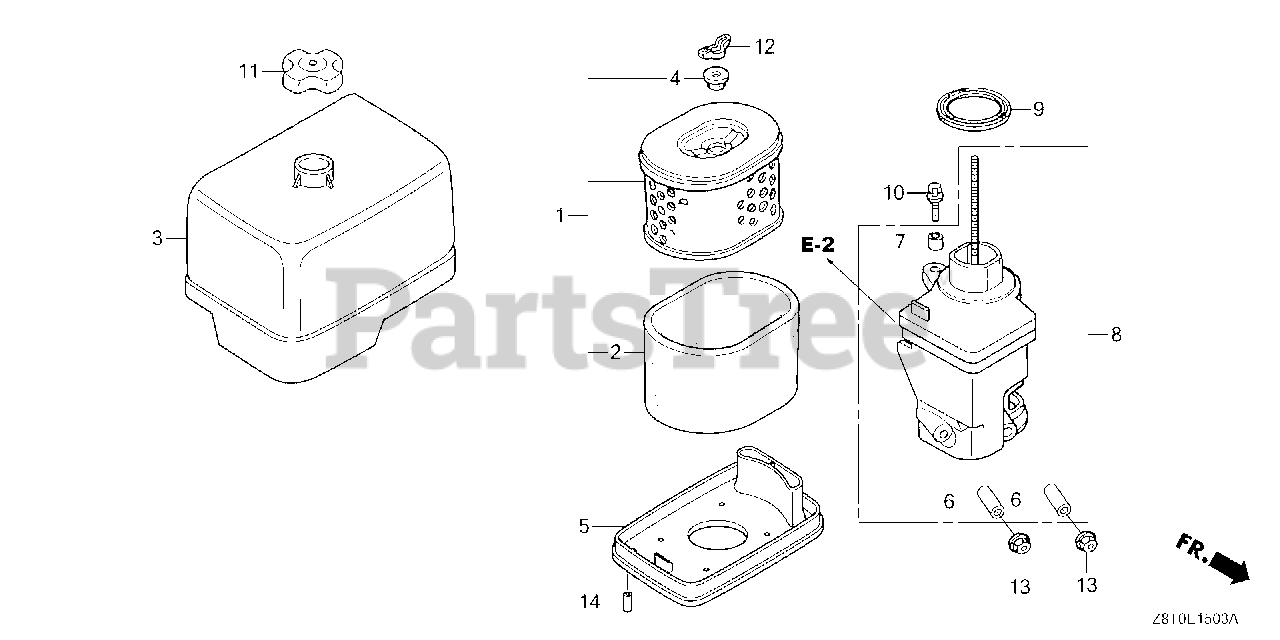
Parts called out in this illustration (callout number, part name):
1	ELEMENT, AIR CLEANER
2	FILTER (OUTER)
3	COVER, AIR CLEANER HOUSING
4	GROMMET, AIR CLEANER
5	NOSE, MUFFLER
6	COLLAR, AIR CLEANER
7	COLLAR B, AIR CLEANER
8	ELBOW, AIR CLEANER
9	GASKET, AIR CLEANER HOUSING
10	BOLT-WASHER (6X22)
11	NUT, AIR CLEANER COVER
12	WINGNUT, TOOL BOX SETTING
13	NUT, FLANGE (6MM)
14	CAP, SEALING
